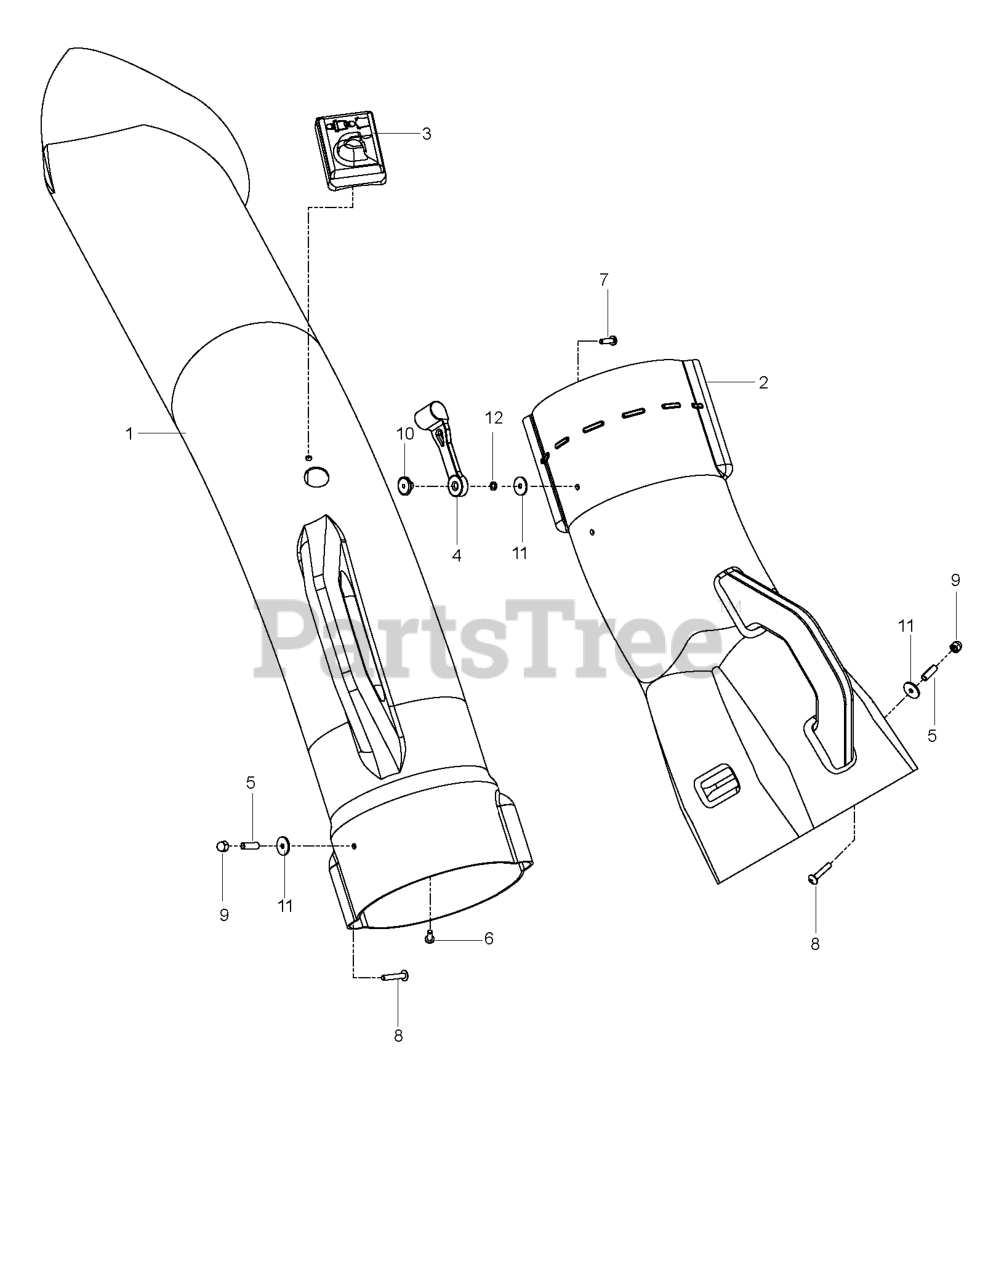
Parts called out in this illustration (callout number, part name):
1	CHUTE, UPPER
2	CHUTE, MIDDLE
3	DUMP BAG INDICATOR
4	HOOD LATCH
5	BSHG .202X.75 LG SPLIT ZD SPEC
6	SCREW
7	SCREW #10-24 X 5/8
8	SCREW #10-24 X 1-1/8 ZD SPEC
9	NUT 10-24 ACORN ZD
10	NUT 10-24 WELD PLATED
12	WASHER - 3/16 LOCK ZD
